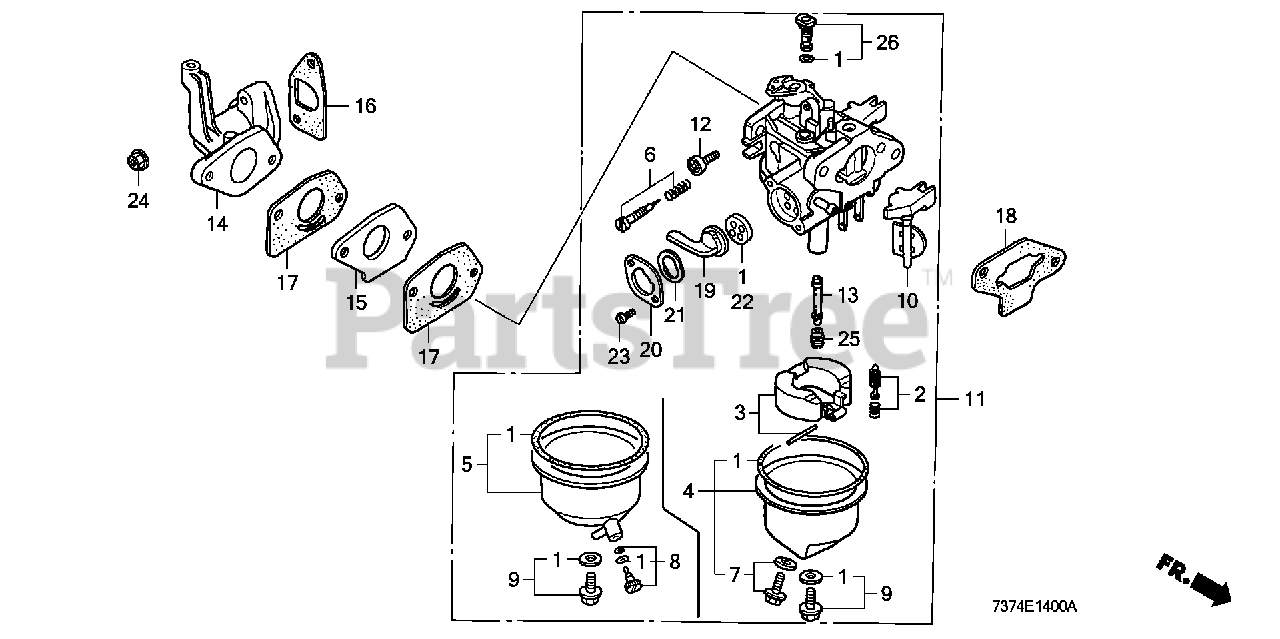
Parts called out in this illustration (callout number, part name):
1	GASKET SET
2	VALVE SET, FLOAT (CARBURETOR NO.) (SEAT NOT INCLUDED)
4	CHAMBER SET, FLOAT (CARBURETOR NO.)
6	SCREW SET, PILOT (Honda Code 1441500). (CARBURETOR NO.)
7	SCREW SET, DRAIN (Honda Code 1672187). (CARBURETOR NO.)
9	SCREW SET (CARBURETOR NO.)
11	CARBURETOR ASSY.
11	CARBURETOR ASSY. (BF05A E)
12	SCREW, THROTTLE STOP
13	NOZZLE, MAIN
14	MANIFOLD, IN.
15	INSULATOR, CARBURETOR
16	GASKET, INSULATOR
17	GASKET, CARBURETOR
18	GASKET, AIR CLEANER
20	PLATE, LEVER SETTING
21	SPRING, PETCOCK LEVER (CARBURETOR NO.)
22	GASKET, VALVE
23	SCREW, PAN (3X5)
24	NUT, FLANGE (5MM)
25	JET, MAIN (#58) (CARBURETOR NO.)
25	JET, MAIN (#60) Use up to Engine SN BF22B C.
25	JET, MAIN (#55) Use from Engine SN BF22B D.
25	JET, MAIN (#55) Use up to Engine SN BF12B C.
26	JET SET, PILOT (#35)
